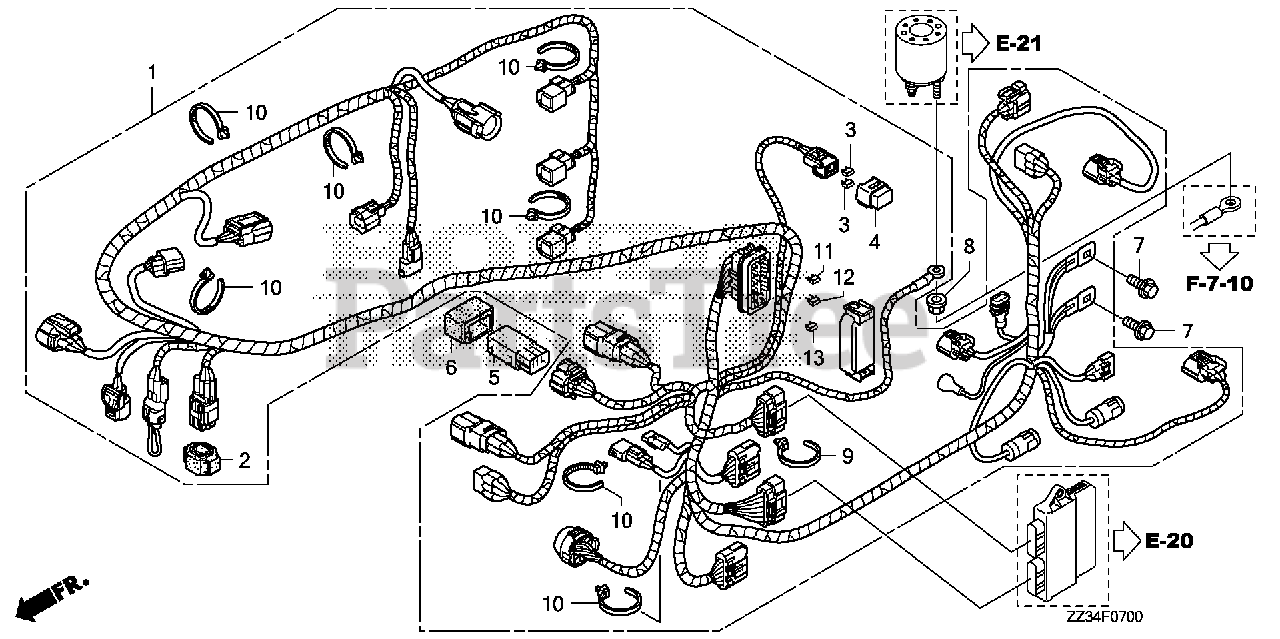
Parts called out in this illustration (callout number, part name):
1	WIRE HARNESS ASSY., MAIN
2	SUSPENSION, CONNECTOR
3	FUSE, BLADE (40A)
4	COVER ASSY., FUSE (40A)
5	RELAY ASSY., MAIN
6	SUSPENSION, RELAY
7	BOLT, FLANGE (6X12)
8	NUT-WASHER (8MM)
9	CLIP, WIRE HARNESS (110MM) (7MM HOLE) (GREEN)
10	CLIP, HARNESS BAND (145MM) (BLACK)
11	FUSE, MINI (10A)
12	FUSE, MINI (15A)
13	FUSE, MINI (30A)
